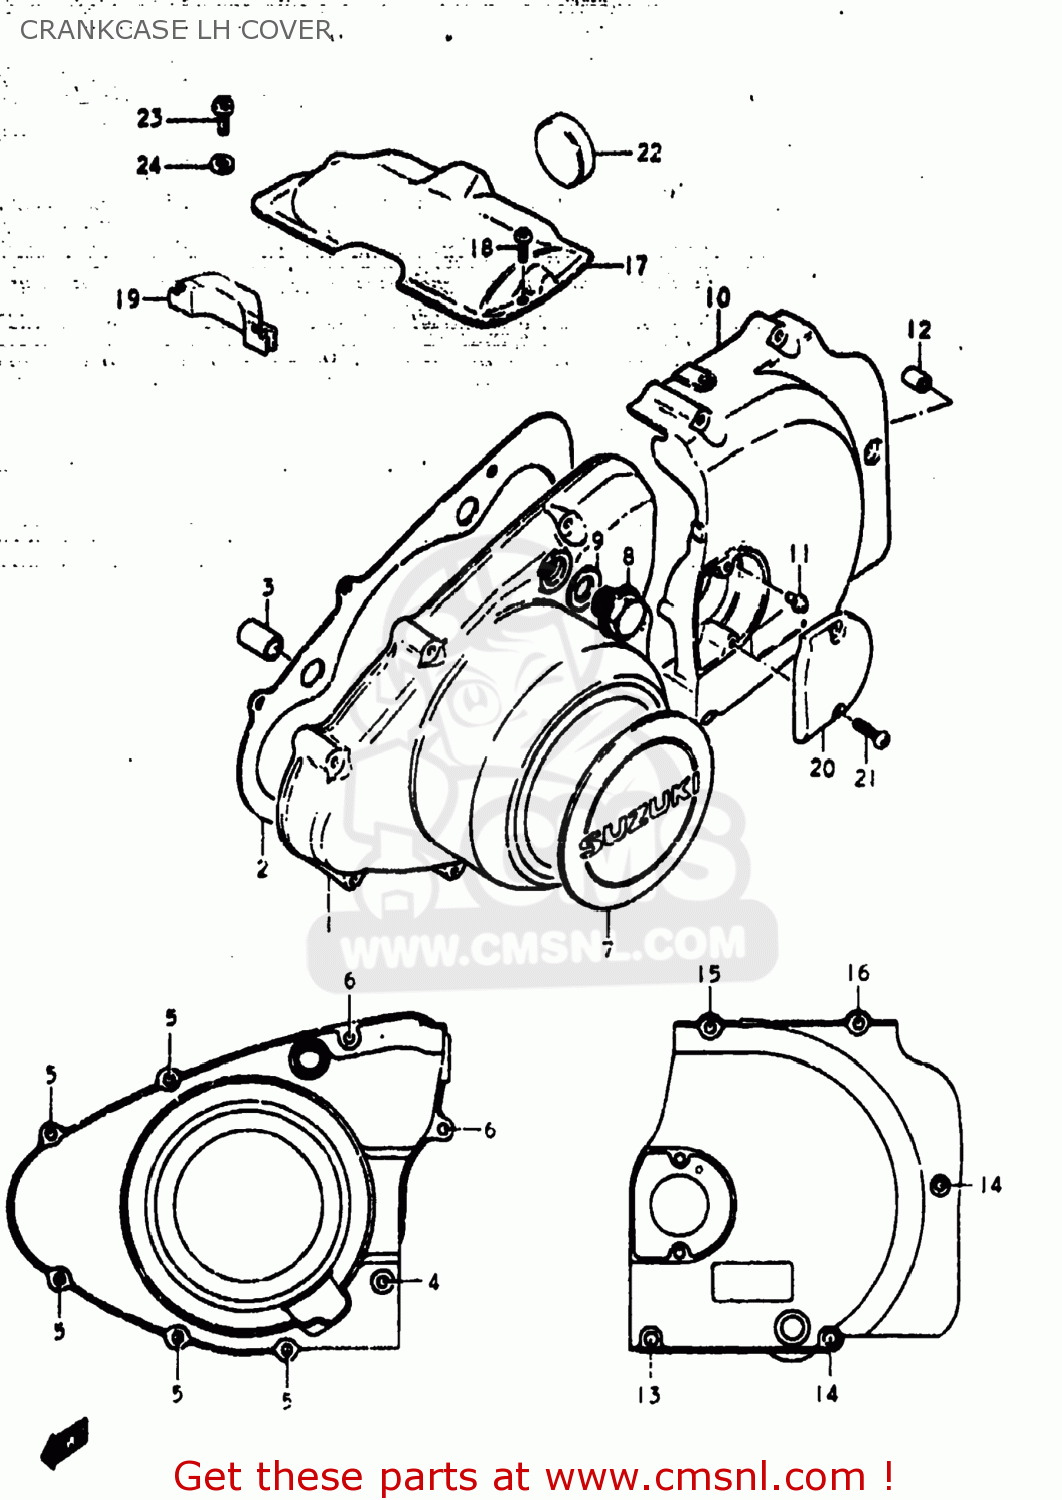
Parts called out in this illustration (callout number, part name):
1	COVER
2	GASKET,MAGNETO COVER (MCA)
3	PIN
4	SCREW
5	SCREW (6X35)
6	SCREW
7	EMBLEM
8	PLUG (14X12)
9	GASKET(14X19.2X2) (NAS)
10	COVER,ENGINE SPROCKET
11	NIPPLE
12	PIN
13	SCREW
14	SCREW 6X60
15	SCREW
16	SCREW
17	COVER,STARTER MOTOR
18	SCREW
19	GROMMET,STARTING MOTOR
20	CAP,CLUTCH RELEASE ADJUST
21	SCREW
22	PLUG
23	SCREW
24	GASKET(6.2X11X1) (NAS)
